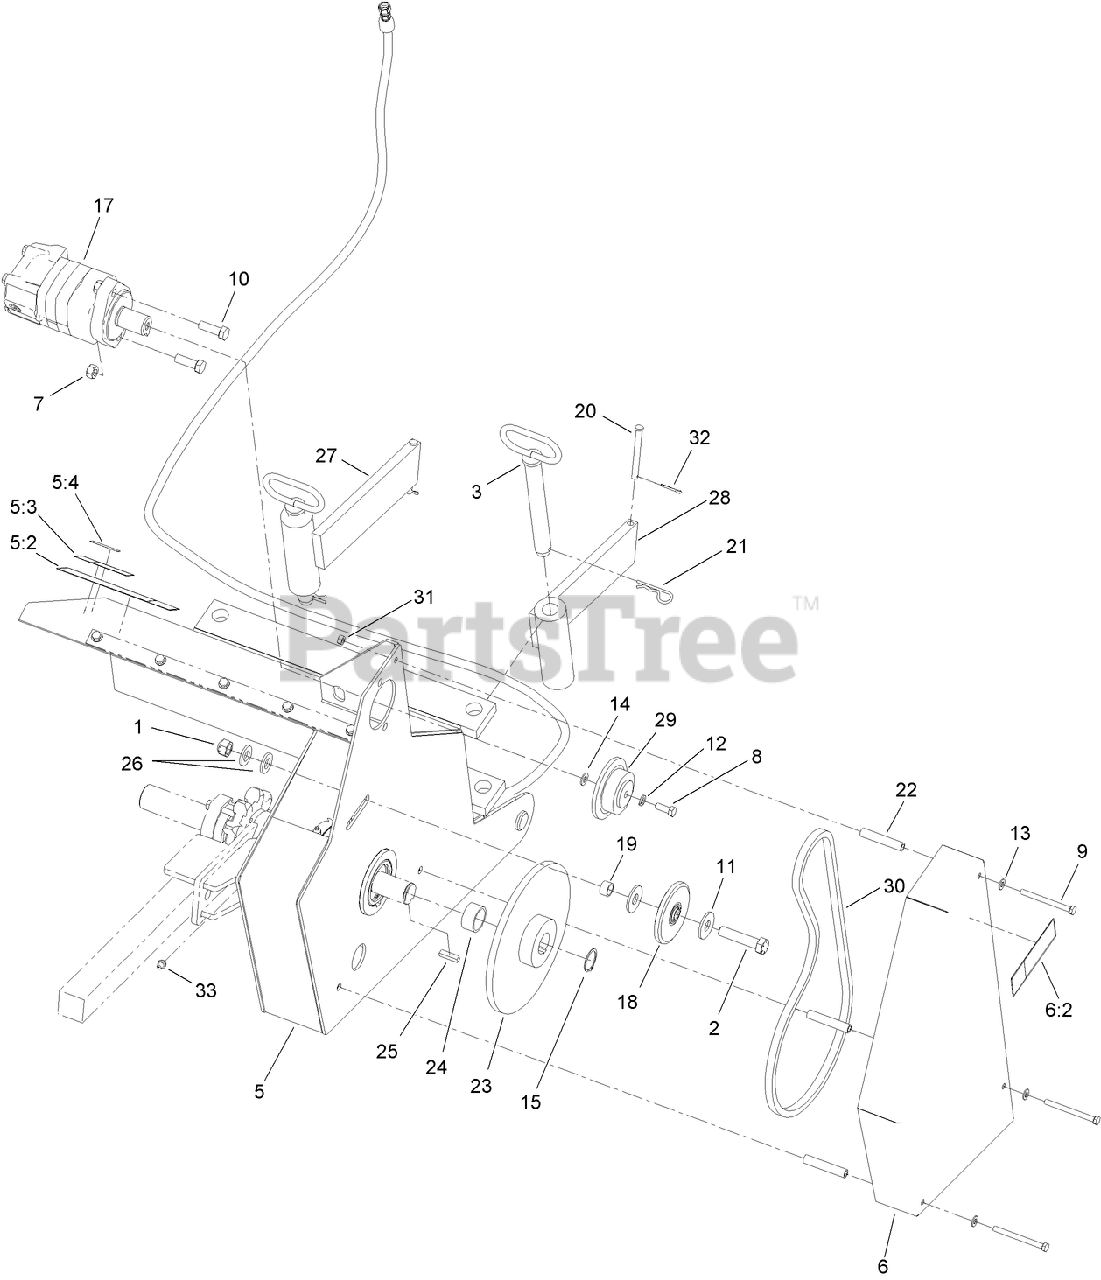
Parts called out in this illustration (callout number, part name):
1	NUT-CROWNLOCK
2	SCREW-HH
3	PIN-MOUNTING
5	FRAME ASM
5:2	DECAL-DANGER, ENTANGLEMENT
5:3	DECAL-DANGER
5:4	DECAL-GREASE
6	COVER ASM
6:2	DECAL-WARNING, CHAIN
7	NUT-LOCK, HEX
8	SCREW-HH
10	SCREW-HH
11	WASHER-FLAT
12	WASHER-LOCK
13	WASHER-PLAIN
14	WASHER-FLAT
15	RING-SNAP, EXTERNAL
17	HYD MOTOR ASM
18	IDLER BEARING AND SPROCKET ASM
19	SPACER-SPROCKET, IDLER
20	PIN-CLEVIS
21	PIN-Hair
23	SPROCKET-HEADSHAFT
26	WASHER-FLAT
27	ARM-MOUNTING, RH
28	ARM-MOUNTING, LH
29	SPROCKET-DRIVE
30	CHAIN-68P
31	NUT-LOCK, CONE
32	PIN-COTTER
33	FITTING-GREASE
